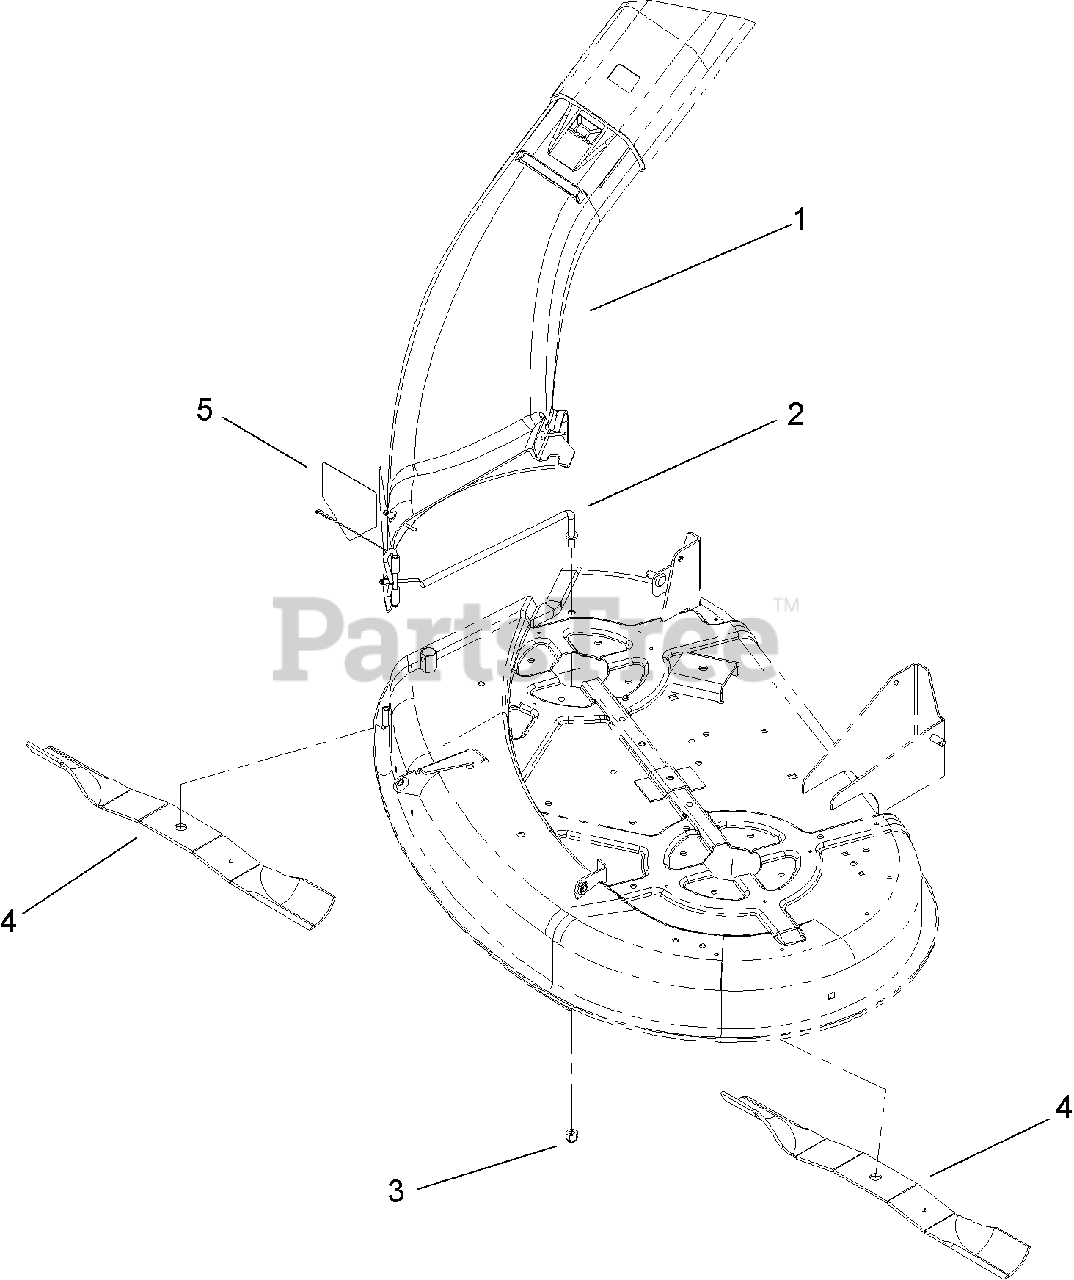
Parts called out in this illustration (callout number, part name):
1	Bagger Chute ASM
2	ROD-PIVOT
3	NUT-LOCK, NI
5	DECAL-DANGER
